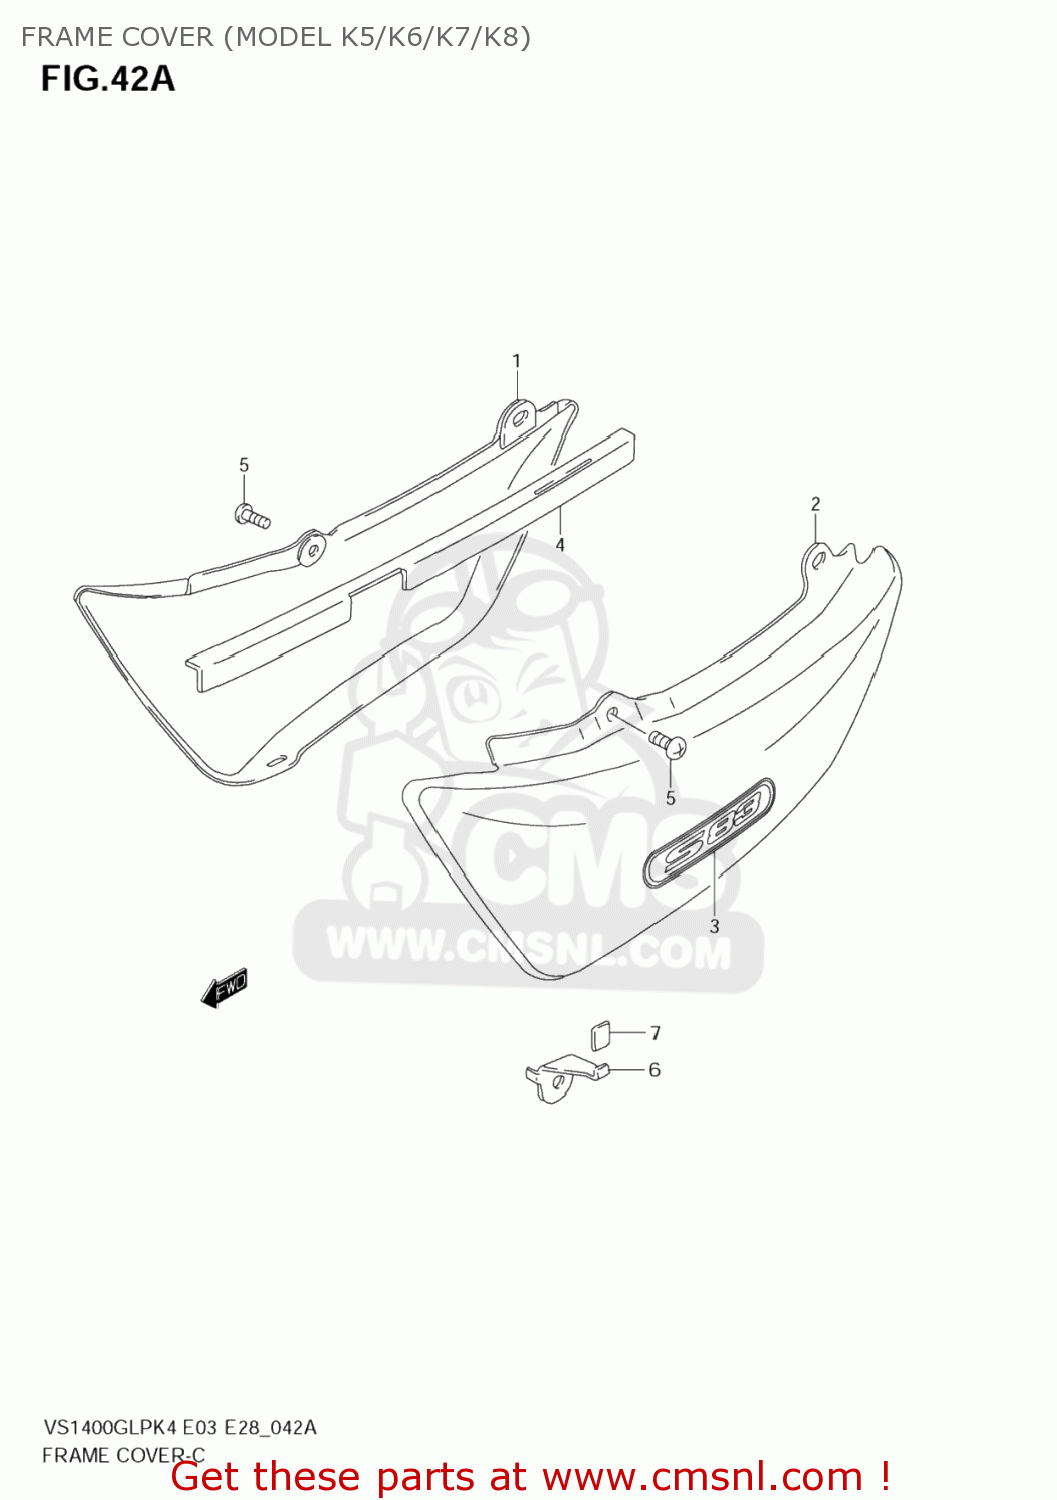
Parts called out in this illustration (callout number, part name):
1	COVER,FRAME,R(RED)
2	COVER,FRAME,L(RED)
3	EMBLEM,FRAME COVER
4	PROTECTOR,FRAME COVER,R
5	SCREW
6	HOOK,FRAME COVER,L
7	CUSHION,FRAME COVER HOOK
